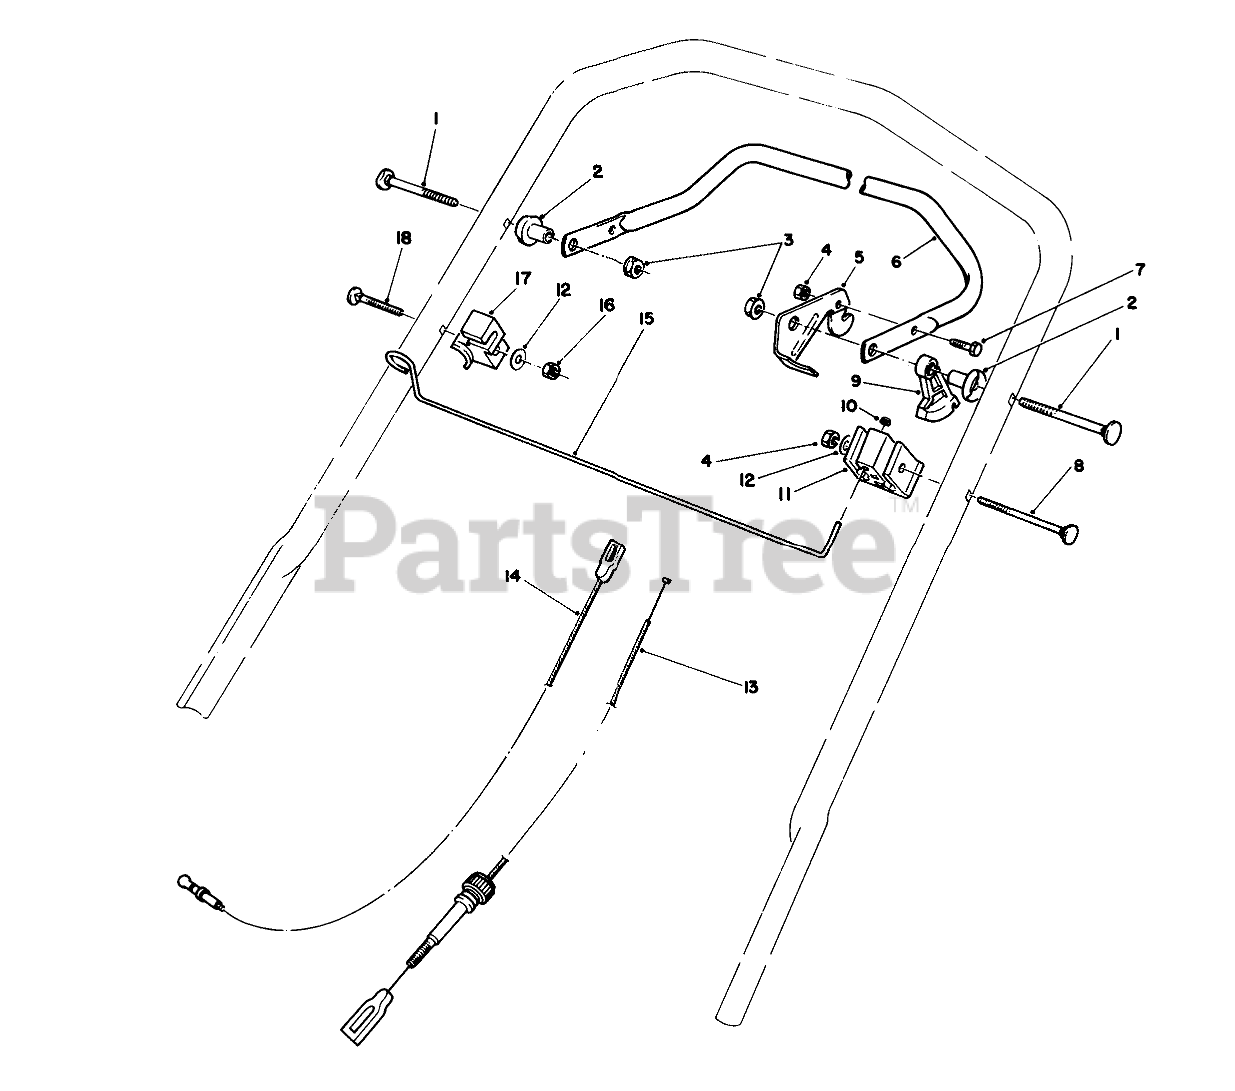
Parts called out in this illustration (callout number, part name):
1	5/16-18 X 2 HNDLE SCREW
2	SPACER-SUPPORT
3	NUT-LOCK, NI
4	NUT-LOCK, NI
5	LEVER-CONTROL
6	Bar-Control
7	SCREW-HH
8	HANDLE SCREW
9	LEVER-TRACTION
10	NUT-SPEED
11	SUPPORT-CABLE
12	WASHER-FLAT
13	CABLE-TRACTION
14	BRAKE CABLE
15	ROPE ROD PLATED
16	NUT-HEX
17	ROD CATCH
18	SCREW-HANDLE
